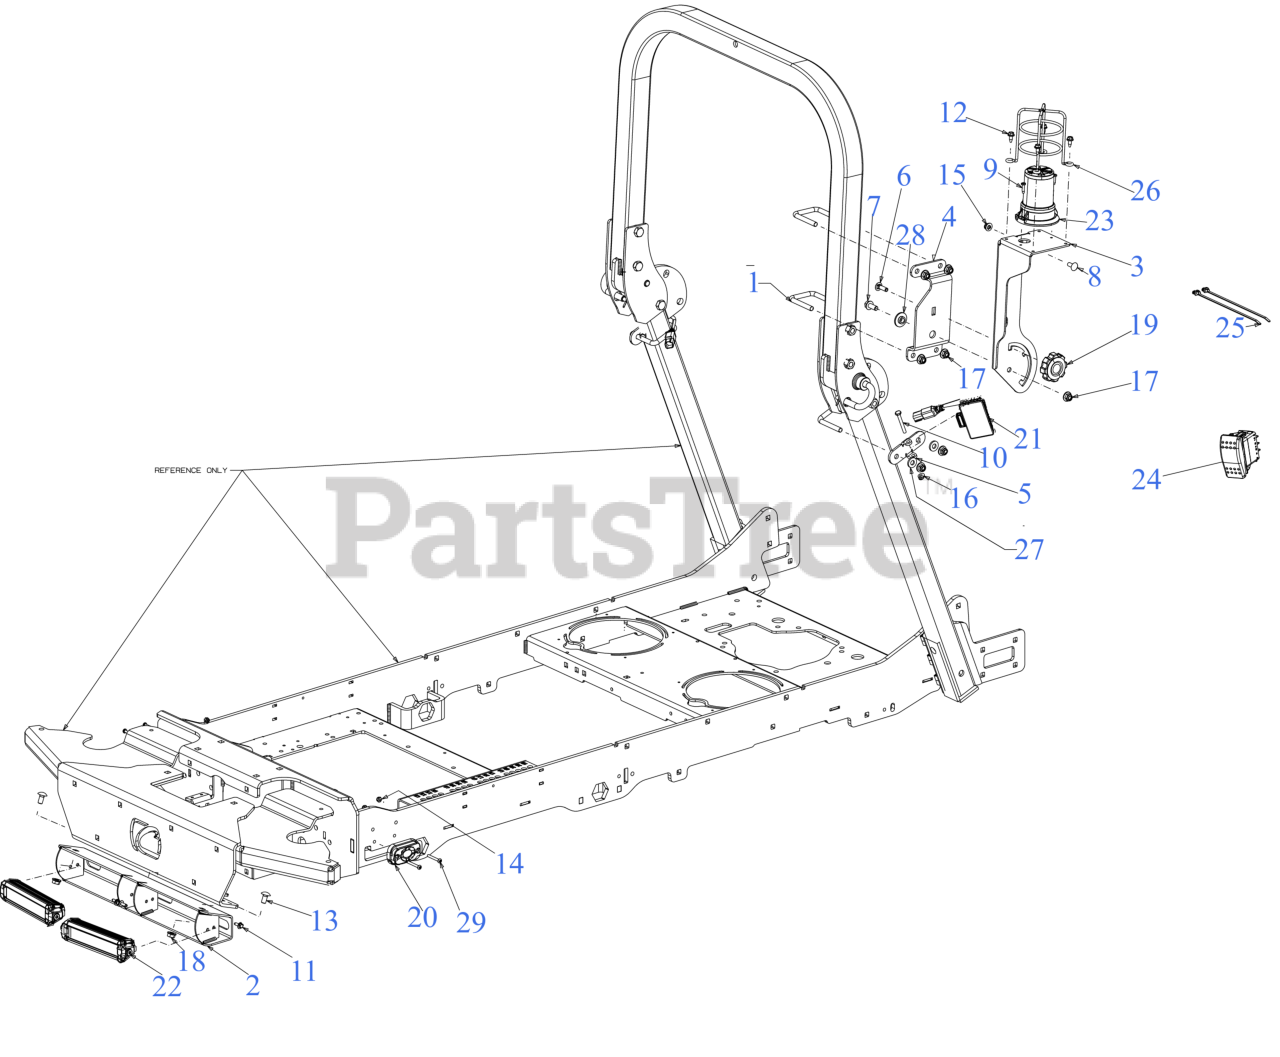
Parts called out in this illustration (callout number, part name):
1	U-BOLT, 3/8-16 X
2	HEADLIGHT BRACKET
3	PIVOT MOUNT BRACKET
4	FIXED MOUNT BRACKET
5	LIGHT MOUNT BRACKET
6	CARRIAGE BOLT 5/16-18 x 1.00
7	SCREW 3/8-16 x .875 GR5
8	CARRIAGE BOLT 5/16-18 x .75
9	SCREW (10-24X.75:PH:TAP:T25:GR5)
10	SCREW 1/4-20 x 2 GR5
11	SCREW M6-1 x .625
12	SCREW 1/4-20X.625
13	CARRIAGE BOLT 3/8-16 x .75
15	FLANGE LOCK NUT 5/16-18
16	FLANGE LOCK NUT
18	HEX LOCK NUT
19	KNOB-5/16-18
20	LED HEADLIGHT (300LM)
21	LED HEADLIGHT (400LM)
22	LED HEADLIGHT (2000LM)
23	LED BEACON LIGHT
24	ROCKER SWITCH
25	CABLE TIE
26	BEACON LIGHT COVER
27	FLAT WASHER
28	SHOULDER SPACER
